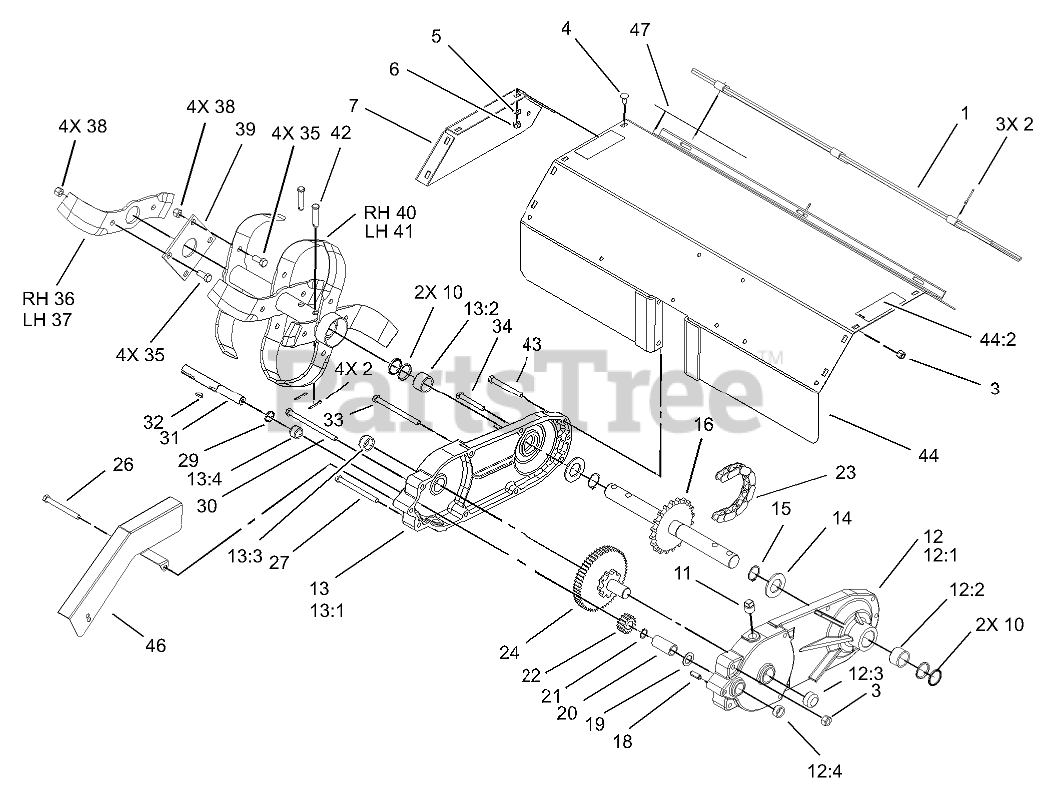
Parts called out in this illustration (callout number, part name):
1	GUARD ASM
2	PIN-COTTER
3	NUT-LOCK, NI
4	BOLT-CARR
5	WASHER-PLAIN
6	NUT-LOCK, NI
7	COVER-TINE END
11	PLUG-PIPE, SQH
12	RH Bearing ASM
12:1	GEARCASE-TILLER
12:2	BEARING-NEEDLE
12:3	BEARING-NEEDLE
12:4	BEARING-NEEDLE
13	LH Bearing ASM
13:1	GEARCASE-TILLER
13:2	BEARING-NEEDLE
13:3	BEARING-NEEDLE
13:4	BEARING-NEEDLE
14	WASHER
15	RING-RETAINING
16	TINE SHAFT ASM
18	PIN-ROLL
19	WASHER-THRUST
20	TUBE-SPACER
21	Ring-Snap
22	GEAR-PINION
23	CHAIN
24	GEAR AND SHAFT ASM
26	SCREW-HH
27	SCREW-HH
29	SEAL-OIL
30	SCREW-HH
31	SHAFT-INPUT
32	KEY-WOODRUFF
33	SCREW-HH
34	SCREW-HH
35	SCREW-HH
36	TINE-RH
37	TINE-LH
38	NUT-LOCK, NI
39	PLATE-TINE MOUNTING
40	RH TINE ASM
41	LH TINE ASM
42	PIN-CLEVIS
43	SCREW-HH
44	TINE SHIELD/DECAL ASM
44:2	DECAL-DANGER
46	GUARD-TILLER
47	DECAL-WORKHORSE
